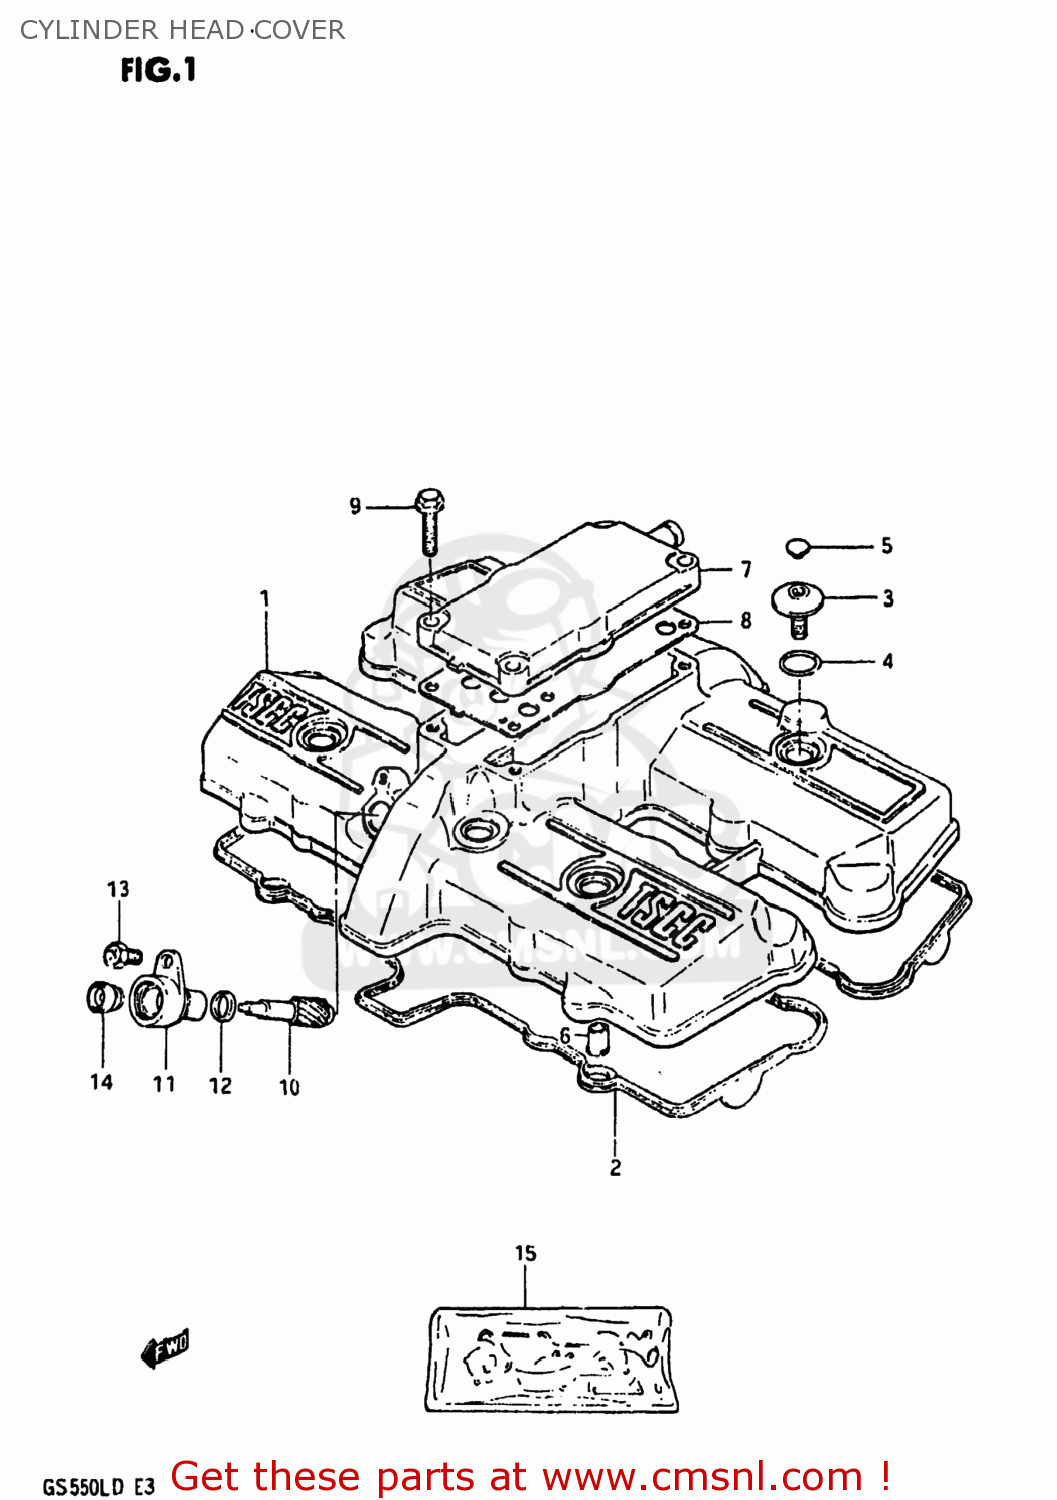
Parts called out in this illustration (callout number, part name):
1	COVER,CYLINDER HEAD
2	GASKET,CYL HEAD COVER (NAS)
3	BOLT(7X5.5)
4	O RING(D:1.9,ID:14.5)
5	CAP(OD:10)
6	PIN
7	COVER,BREATHER
8	GASKET (MCA)
9	BOLT,REAR
10	GEAR,TACHOMETER DRIVEN
11	SLEEVE,TACHOMETER DRIVE GEAR
12	SEAL,TACHOMETER DRIVEN
13	SCREW(5X12)
14	SEAL,OIL(5X12X8)
15	GASKET SET (MCA)
